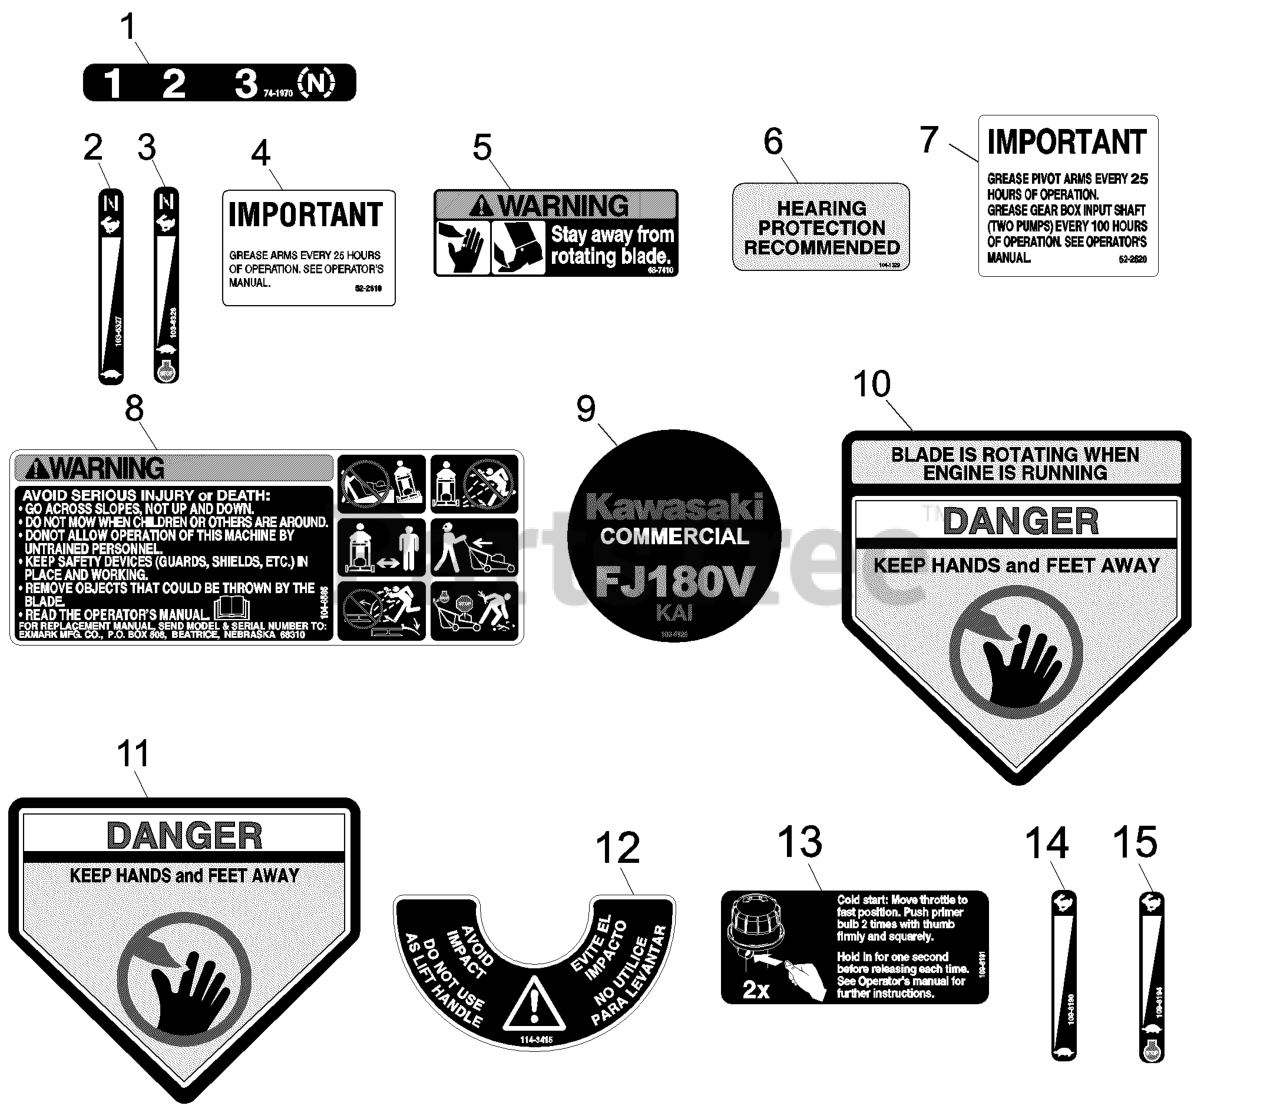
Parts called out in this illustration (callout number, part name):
1	DECAL-POSITION, GEAR
2	DECAL,THROTTLE/CHOKE
3	DECAL-THROTTLE / CHOKE
4	LABEL-GREASE, HP
5	DECAL-BLADE
6	DECAL-PROTECTION, HEARING
7	Label, Grease
8	DECAL-WARNING
9	DECAL
10	DECAL-DANGER
11	DECAL-DANGER
12	DECAL
13	DECAL, PRIMER
14	DECAL, THROTTLE CONTROL Z
15	DECAL THROTTLE CONTROL BB
